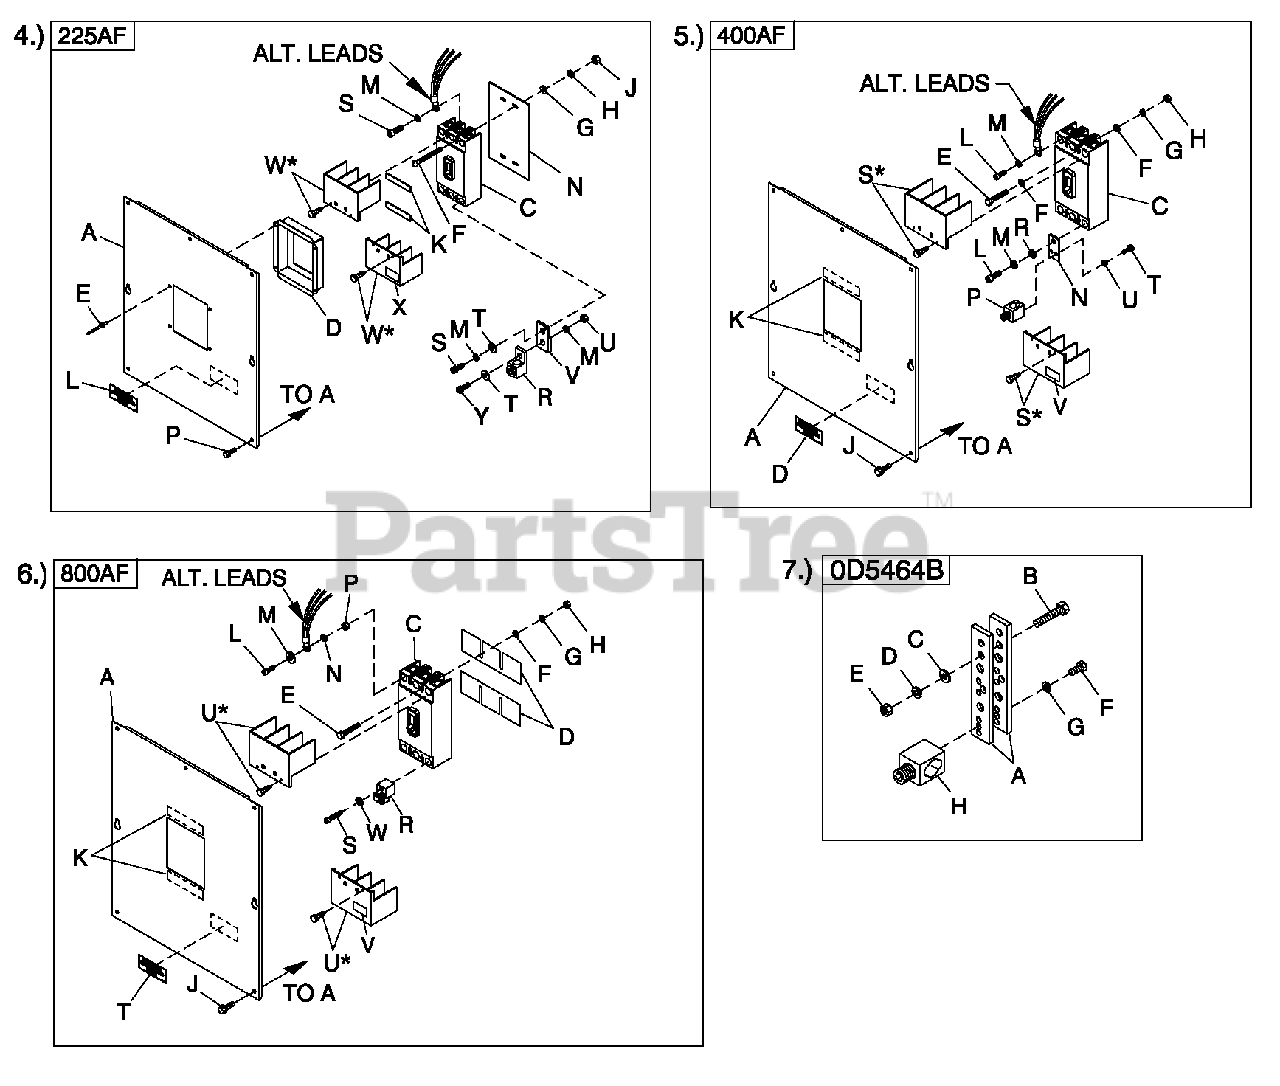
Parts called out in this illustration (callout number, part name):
A	COVER CBC5 225AF
C	CIRCUIT BREAKERS 200A FRAME
D	COVER CB DISH 225AF
E	RIVET PO P .125 X .275 SS
F	SCREW RHM #8-32X3-1/4
G	WASHER FLAT #8 ZINC
H	WASHER LOCK #8-M4
J	NUT HEX #8-32 STEEL
K	TAPE ELEC 1/2 FOAM
L	DECAL CUSTOMER CONNECT INSIDE
M	WASHER LOCK M8-5/16
N	INSULATOR CB225AF
P	SCREW THF M6-1 X 16 N WA Z/JS
R	LUG SLDLSS 300 MCM-6 AL/CU
S	SCREW SHC M8-1.25X20G8
T	WASHER FLAT 5/16-M8 ZINC
U	NUT HEX M8-1.25 G8 CLEAR ZINC
V	BUS BAR 200A LUG ADAP TOR
W	TERMINAL COVER CB
X	DECAL TERMINAL SHOCK HZD BI
Y	SCREW SHC M8-1.25X25G12.9
A	COVER CBC5 400AF
C	CIRCUIT BREAKERS 400A FRAME
D	DECAL CUSTOMER CONNECT INSIDE
E	SCREW RHM 1 0-32X4
F	WASHER FLAT #10 ZINC
G	WASHER LOCK #10
H	NUT HEX #10-32 STEEL
J	SCREW THF M6-1 X 16 N WA Z/JS
L	SCREW SHC M10-1.5X25G12.9
M	WASHER LOCK M10
N	BUS BAR CB ADAP TER 225-400 A
P	LUG SLDLSS 600/250-1/0 X 1/4-28
R	WASHER FLAT 3/8-M10 ZINC
S	TERM COVER CB
T	SCREW HHC 1/4-28 X 1/2 G5
U	WASHER LOCK M6-1/4
V	DECAL TERMINAL SHOCK HZD BI
A	COVER CBC5 800AF
C	CIRCUIT BREAKERS 800A FRAME
D	INSULATOR CB800AF
E	SCREW RHM 1/4-20X3-1/2
F	WASHER FLAT 1/4-M6 ZINC
G	WASHER LOCK M6-1/4
H	NUT HEX 1/4-20 STEEL
J	SCREW THF M6-1X16 N WA Z/JS
L	SCREW SHC M10-1.50X 40 G12.9
M	WASHER FLAT 3/8-M10ZINC
N	WASHER LOCK 3/8
P	NUT HEX M10-1.5 G8YEL CHR
R	LUG SLDLSS 3/0-400X3 MCM AL/CU
S	SCREW SHC M6-1.0X50G8.8
T	DECAL CUSTOMER CONNECT INSIDE
U	TERM COVERVITZROTECH 400AF CB
W	WASHER LOCK M6-1/4
A	BUS BAR NEUTRAL BLOCK 390
B	SCREW HHC M8-1.25 X 45 G8.8 FT
C	WASHER FLAT 5/16-M8ZINC
D	WASHER LOCK M8-5/16
E	NUT HEX M8-1.25 G8YEL CHR
F	SCREW HHC 1/4-28 X 3/4 G5
H	LUG SLDLSS 600/250-1/0X1/4-28
